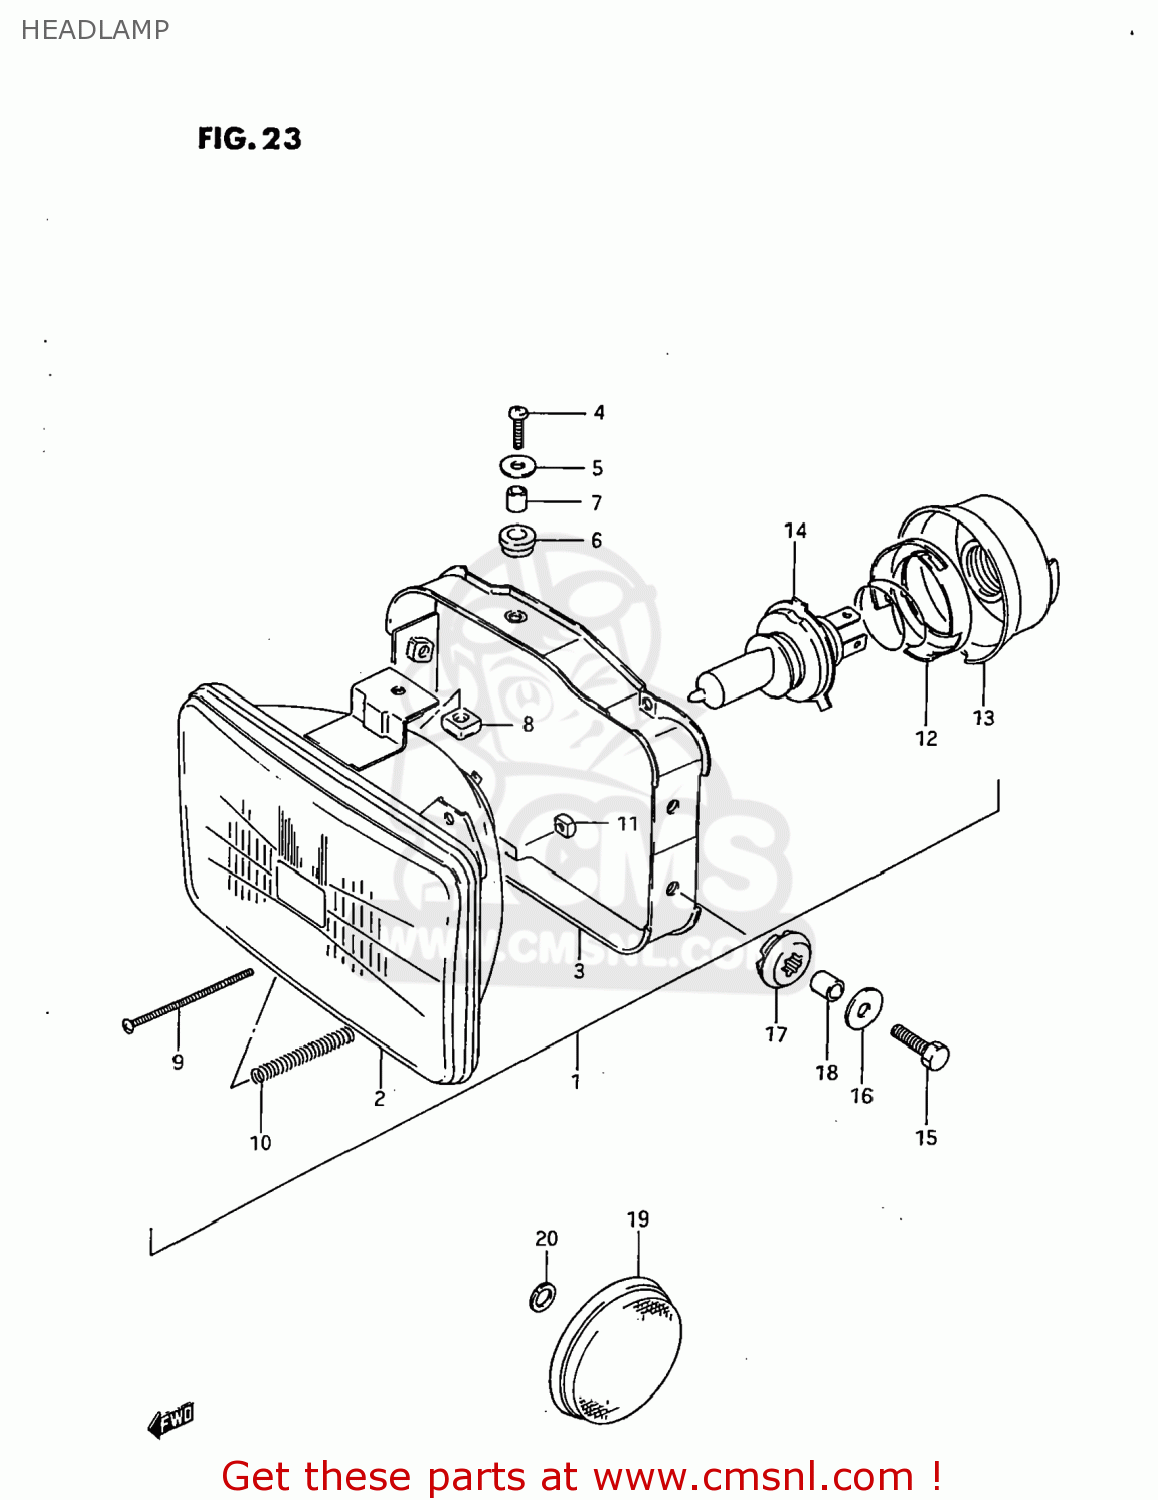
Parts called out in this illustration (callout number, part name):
1	HEADLAMP ASSEMBLY
2	LAMP UNIT
3	HOUSING
4	SCREW 5X20
5	WASHER
6	CUSHION
7	SPACER
8	NUT
9	SCREW,HEADLAMP ADJUST
10	SPRING
11	NUT
12	HOLDER,BULB
13	COVER,SOCKET
14	BULB(12V60/55W,H4)
15	BOLT
16	WASHER (6.5X20X1.2)
17	CUSHION
18	SPACER (6.8X10X10)
19	REFLEX REFLECTOR,FR
20	LOCK WASHER
